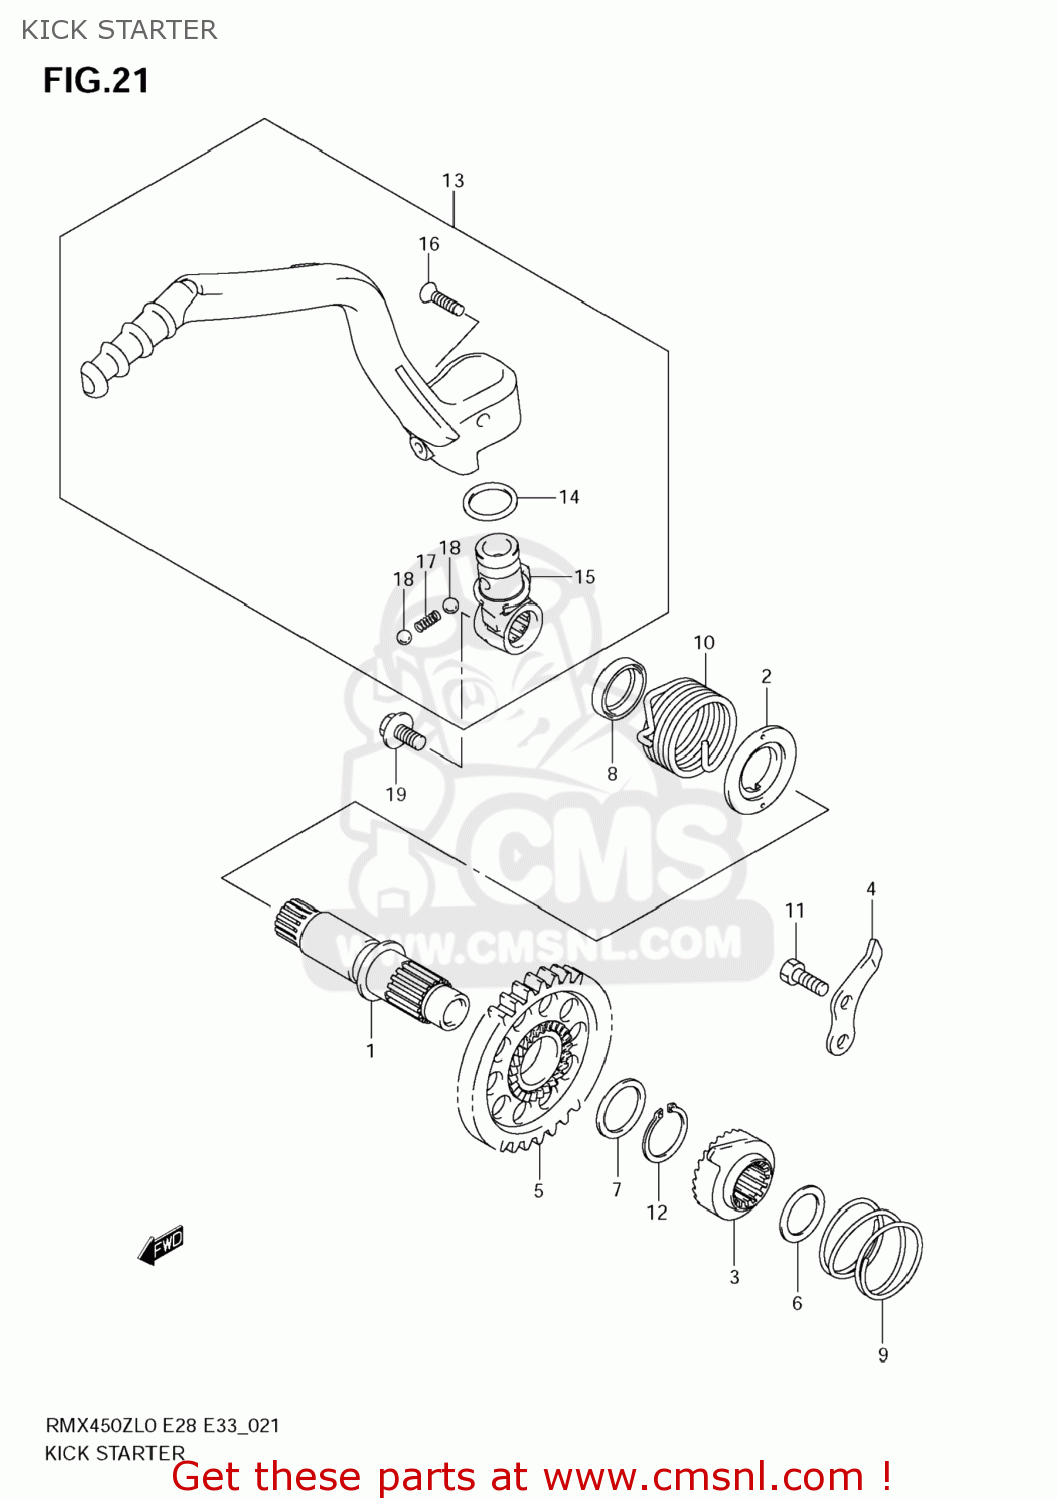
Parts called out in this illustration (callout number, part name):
1	SHAFT,KICK STARTER
2	GUIDE,KICK STARTER SFT SPRING
3	STARTER,KICK
4	GUIDE,KICK STARTER
5	GEAR,KICK STARTER DRIIVE
6	SHIM(17X24X0.5)
7	SHIM(20X26X1)
8	SEAL,OIL(20X27X5)
9	SPRING
10	SPRING
11	BOLT
12	CIRCLIP
13	LEVER ASSY,KICK STARTER
14	O RING,KICK STARTER
15	JOINT,KICK STARTER LEVER
16	SCREW(6X27.5)
17	SPRING
18	BALL
19	BOLT(8X14)
